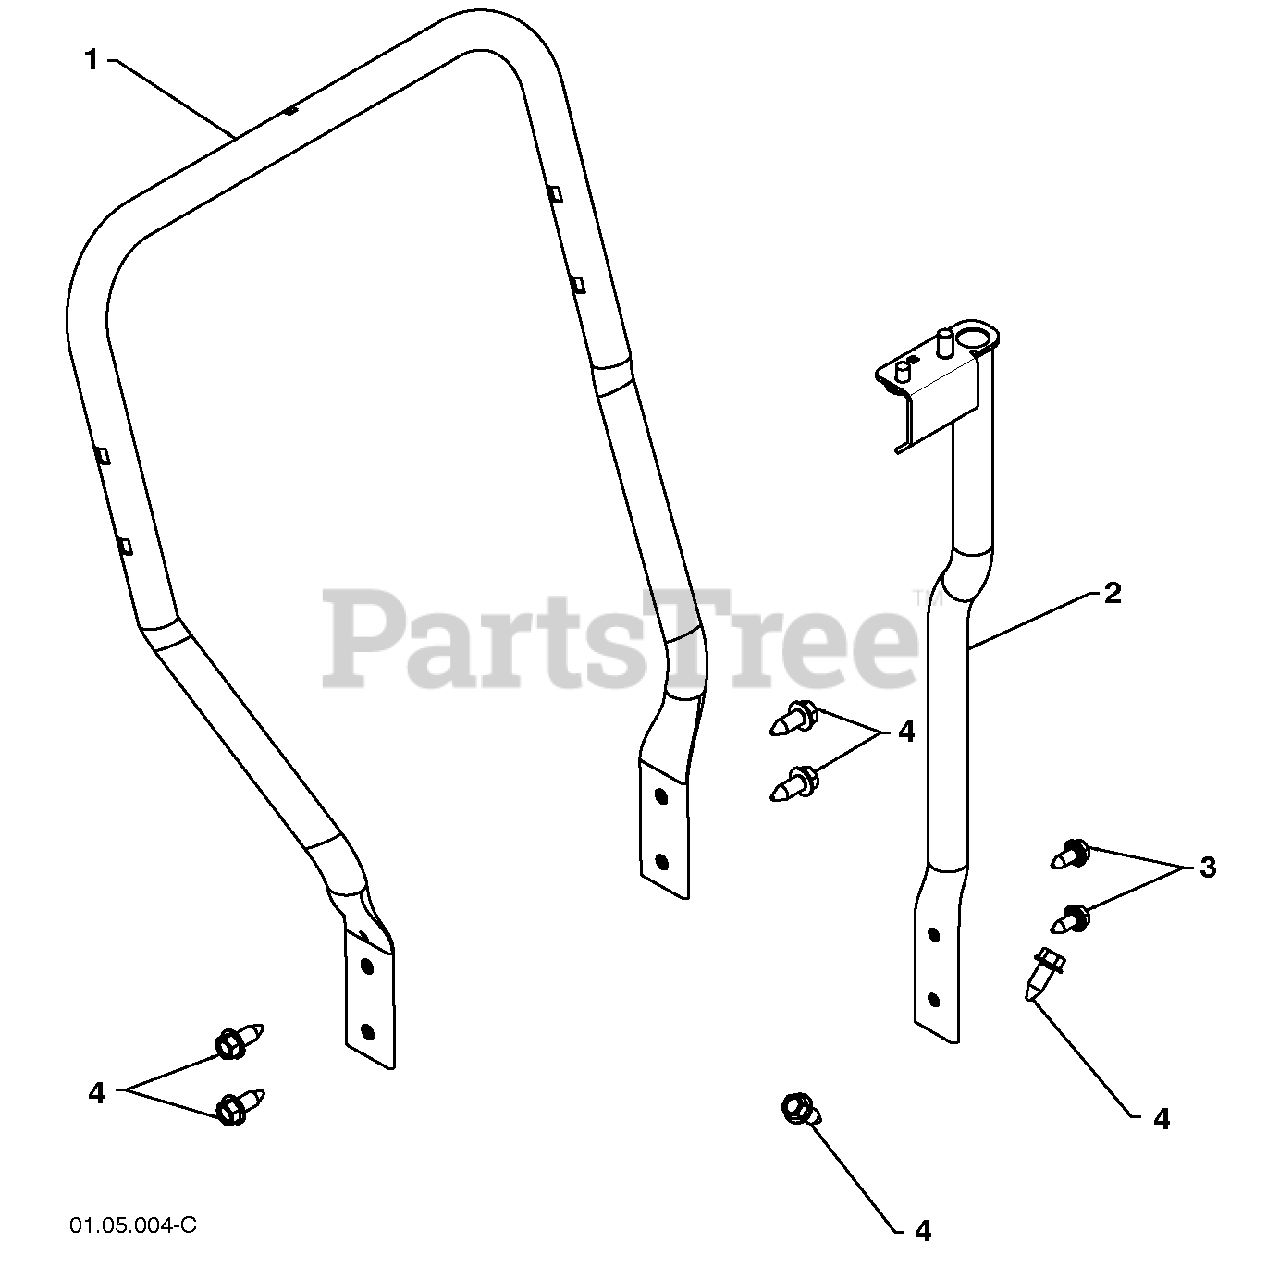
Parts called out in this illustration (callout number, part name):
1	LOWER TUBE
3	BOLT 5/16-18 X .750
4	SCREW 3/8-16 X 1.00
